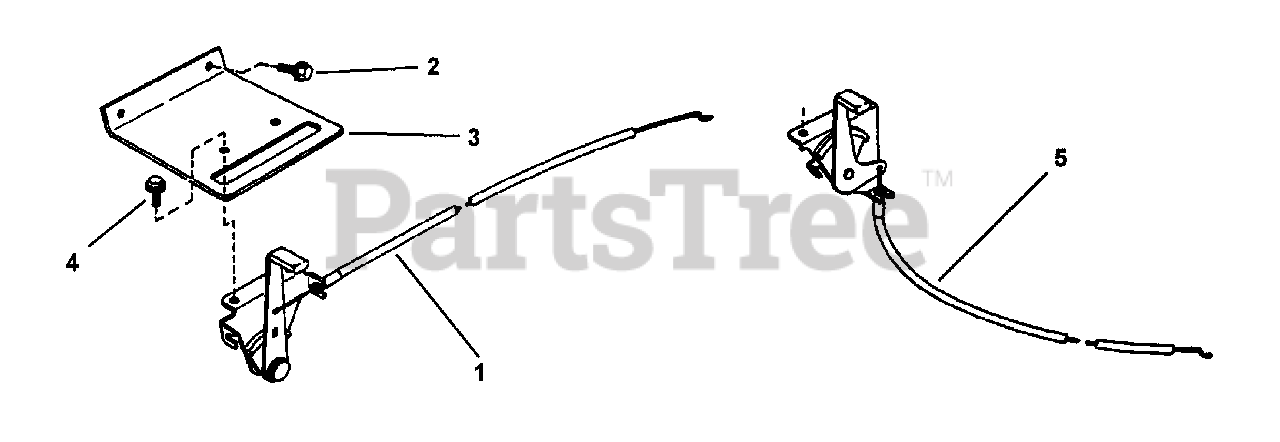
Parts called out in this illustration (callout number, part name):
1	CONTROL, Throttle Manual Start
2	SCREW, 1/4-20 x 1/2" Hex Washer Self-Tap
3	PLATE, Throttle Control
4	SCREW, #10-24 x 1/2" Hex Washer Self-Tap (Torx)
5	CONTROL, Throttle
